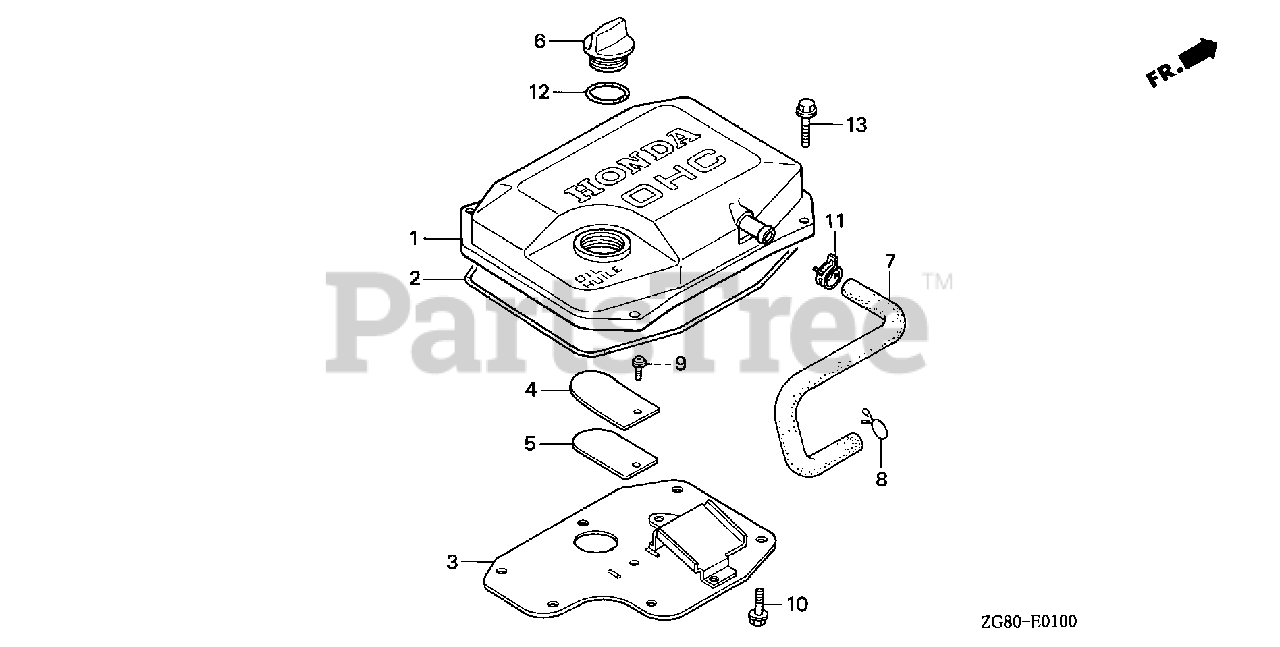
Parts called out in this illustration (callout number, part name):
1	COVER, CYLINDER HEAD
2	GASKET, HEAD COVER
3	COVER, BREATHER
4	STOPPER, VALVE
5	PLATE, VALVE
6	CAP, OIL (GRAY)
9	SCREW-WASHER (5X8)
10	BOLT, FLANGE (6X10)
12	O-RING (26X2.7)
13	BOLT, FLANGE (6X25)
